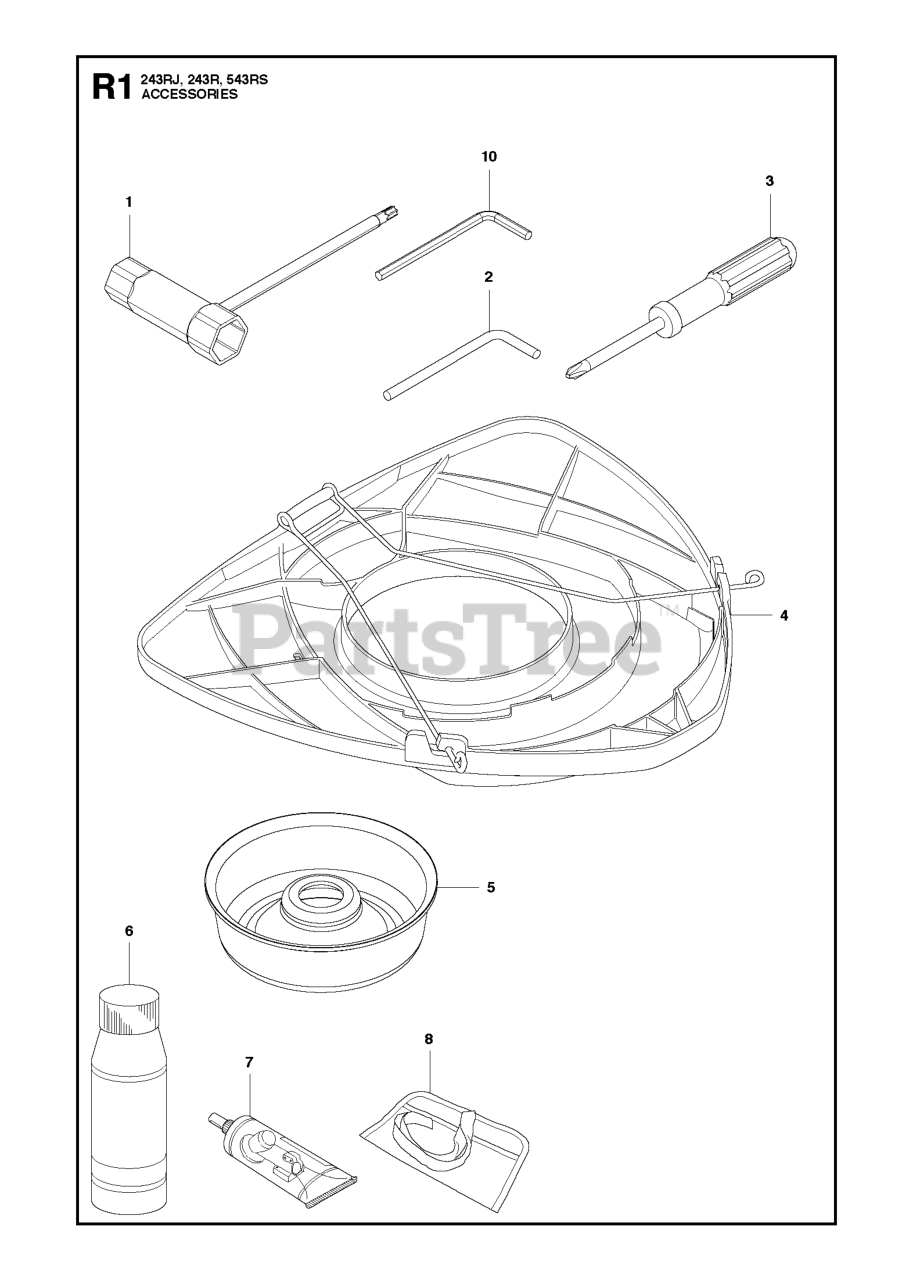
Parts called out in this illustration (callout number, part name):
4	TRANSPORT GUARD
5	SUPPORT CUP
6	Air Filter Oil 1l.
7	BEVEL GEAR GREASE
9	Harness-w/o warning
10	WRENCH
